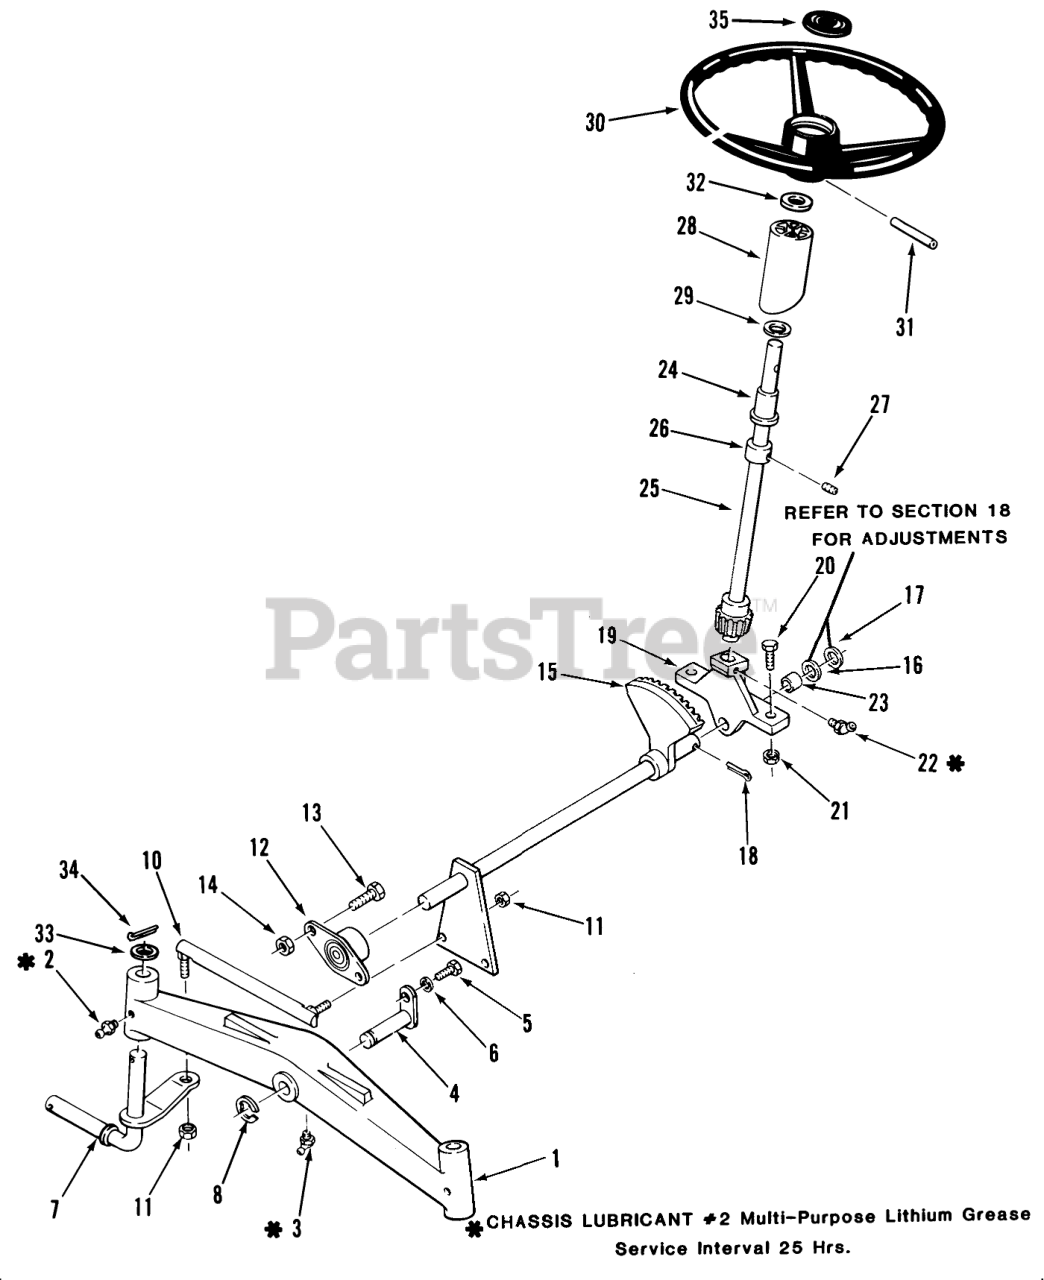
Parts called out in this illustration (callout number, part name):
3	FITTING-GREASE
4	PIN AND PLATE ASM
8	E-RING
12	BEARING-FLANGED
16	WASHER-SHIM
17	WASHER
22	FITTING-GREASE
23	BEARING-BRONZE
24	BEARING-FLANGED
29	WASHER-BOWED
30	DISCONTINE
32	WASHER-FLAT
33	WASHER
34	COTTER PIN-4
